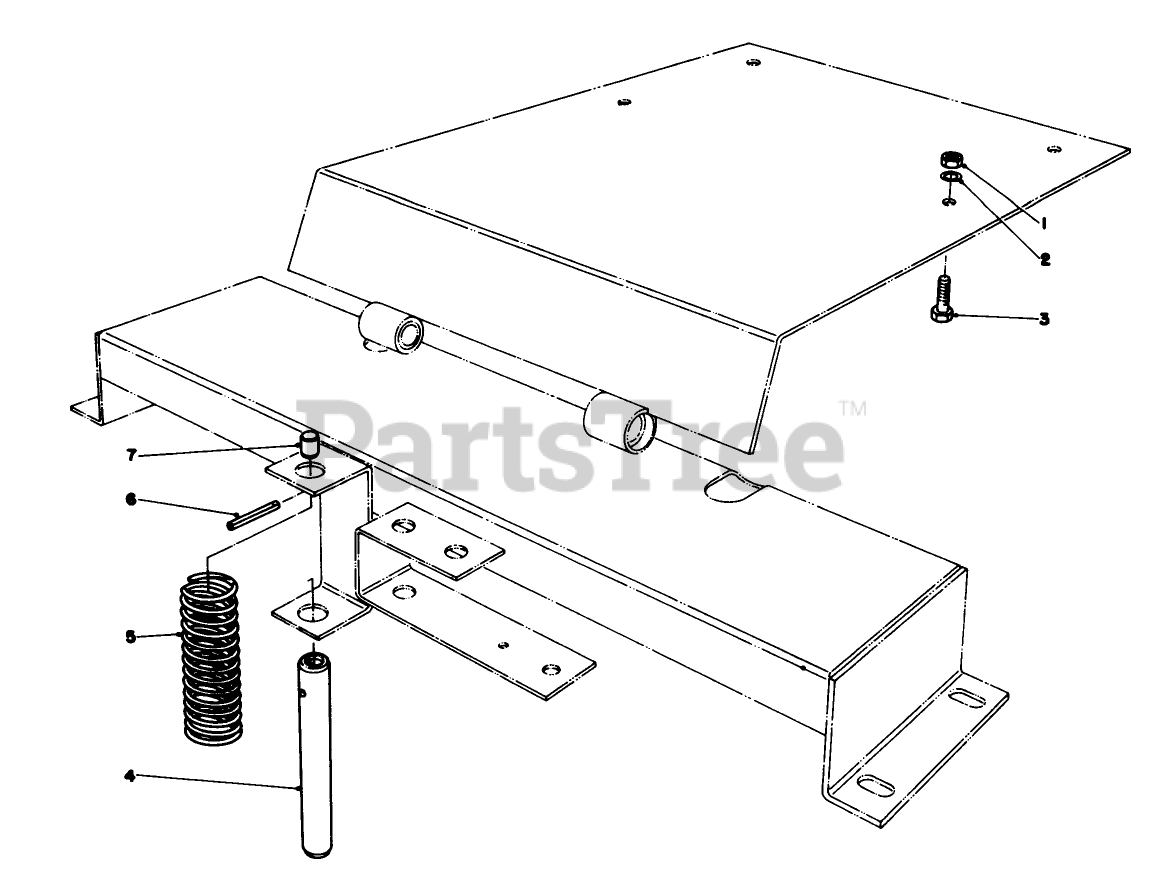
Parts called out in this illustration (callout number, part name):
1	NUT-HEX
2	WASHER-LOCK/SP
3	SCREW-HH
4	PIN-SWITCH, SEAT
5	COMP SPRING
6	PIN-ROLL, SLOTTED
7	PIN-PEDAL
